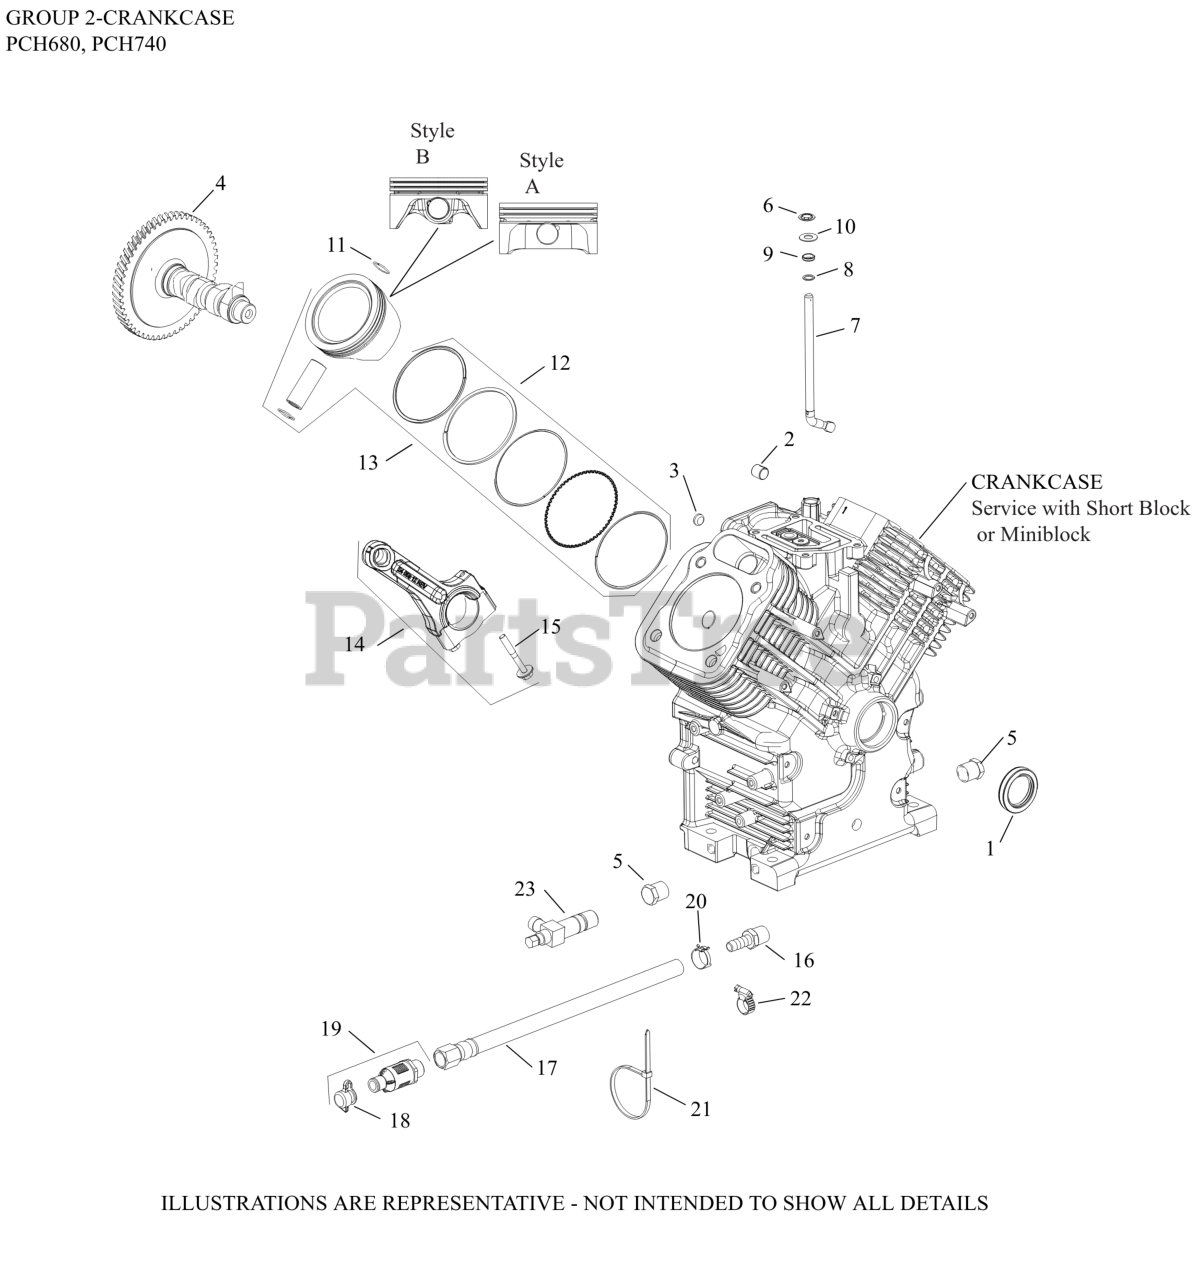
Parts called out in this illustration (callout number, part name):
1	SEAL, OIL (HELIX LIP)
2	PIN, LOCATING
3	PLUG, CUP
4	KIT, CAMSHAFT
5	PLUG, HD PIPE 3/8"
6	RETAINER, RING
7	SHAFT, GOVERNOR CROSS
8	WASHER, FLAT 11/32"
9	SEAL, GOVERNOR CROSS SHAFT
10	WASHER, FLAT 9 MM
11	RETAINER, PISTON PIN
12	RING DISC USE PISTON ASSY PER SPEC
12	RING SET(.08)STYLE A-1.5mm Tp RING THICK
12	RING SET(.25)STYLE A-1.5mm Tp RING THICK
12	RING SET(.50)STYLE A-1.5mm Tp-(#DSC)
12	RING SET(STD)STYLE B-1.2mm Tp RING THICK
12	RING SET(.08)STYLE B-1.2mm RING THICK
12	RING SET(.25)STYLE B-1.2mm Tp RING THICK
12	RING SET(.50)STYLE B-1.2mm Tp RING THICK
13	KIT,PSTN/RNG STYLE A(STD)(#2587406S)
13	KIT,PSTN/RNG STYLE A(.08)
13	KIT,PSTN/RNG STYLE A(.25)USE 2587411-S
13	KIT,PSTN/RNG STYLE A(.50)(#2587404S)
13	KIT,PSTN/RNG STYLE B(STD)
13	KIT,PSTN/RNG STYLE B(.08)
13	KIT,PSTN/RNG STYLE B(.25)
13	KIT,PSTN/RNG STYLE B(.50)
14	ROD, ASSEMBLY CONNECTING
15	KIT, ROD BOLTS-(#25086677S)
